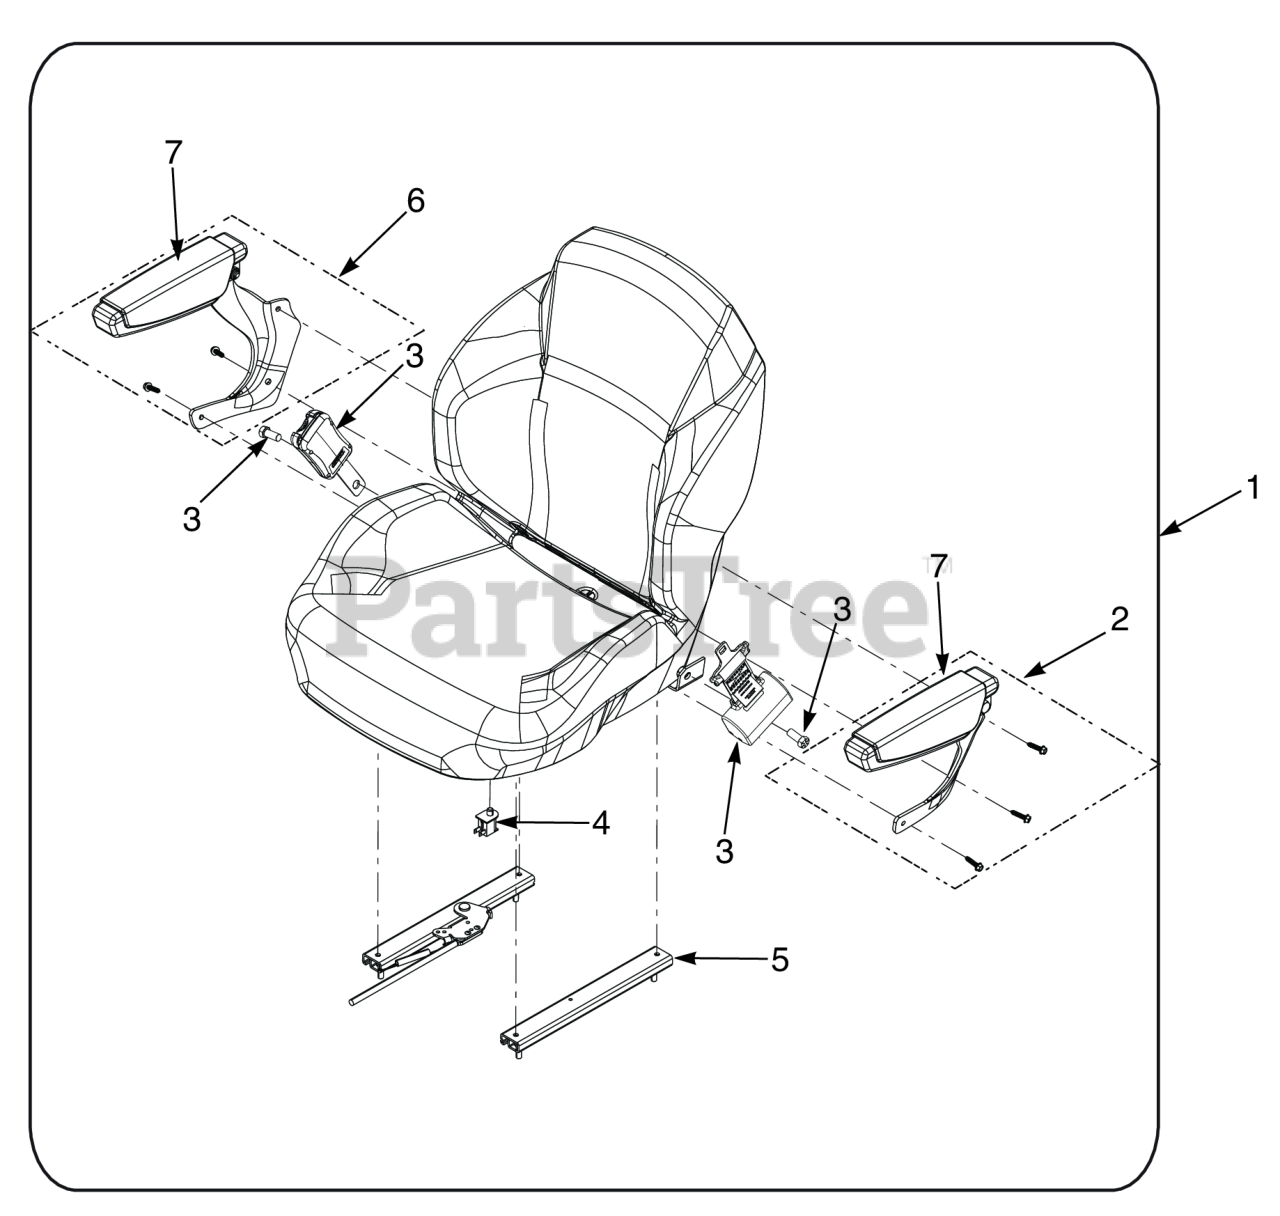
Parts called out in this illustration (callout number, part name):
1	Seat Assembly (INCL 14)
2	Armrest Kit, LH
3	Seat Belt Kit, Retractable - SCZII
4	Switch, Interlock, Normally Open
5	Track Kit
6	Armrest Kit, RH
7	Pad, Armrest
